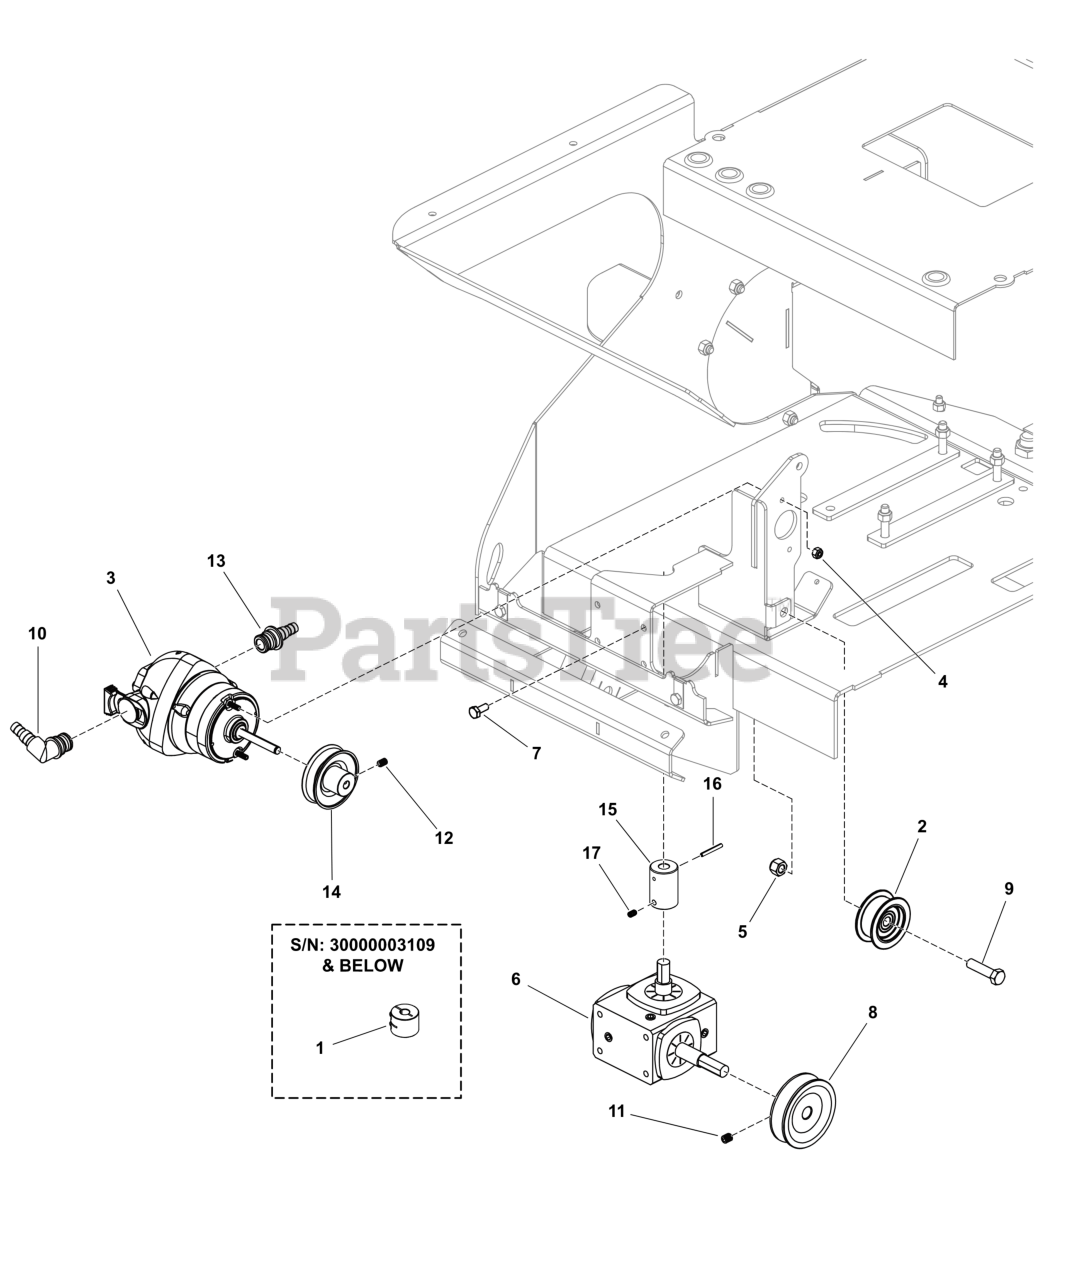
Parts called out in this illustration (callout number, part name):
1	KIT, PLATTER SHAFT COUPLING
2	PULLEY IDLER 1.75" OD X 3/8" BORE
3	PUMP, PULLEY DRIVEN, 1.86 GPM
4	NUT-HEX-NYLK, #10-24 SS188
5	NUT-HEX-NYLK, .375"-16 SS188
6	GEAR REDUCER W/ Ø.375" SHAFT
6	GEAR REDUCER W/ Ø.500" SHAFT
6	GEAR REDUCER W/ 2.50" LONG Ø.500" SHAFT
7	SCR-CAP, HEX .250"-20 X .625" SS188
8	PULLEY, 2.95" O.D. x 0.500" I.D. V, A/B
9	SCR-CAP, HEX .375"-16 X 1.500" SS188
10	FITTING, QUICK RELEASE 3/8 BARB 90 ELBOW
11	SCR-SH, SET .3125"-18 X .375" KCPT SS188
12	SCR-SH, SET .250"-20 X .375" KCPT SS188
13	FITTING, QUICK RELEASE 3/8 BARB STRAIGHT
14	PULLEY, 2.50" OD X .315 ID V, A/B
15	COUPLING, SS, PLATTER SHAFT
16	PIN, COILED SPG, SS, .125" DIA X 1.00"LG
17	SCREW, SET, .190" DIA X .3125" LG. 18-8
